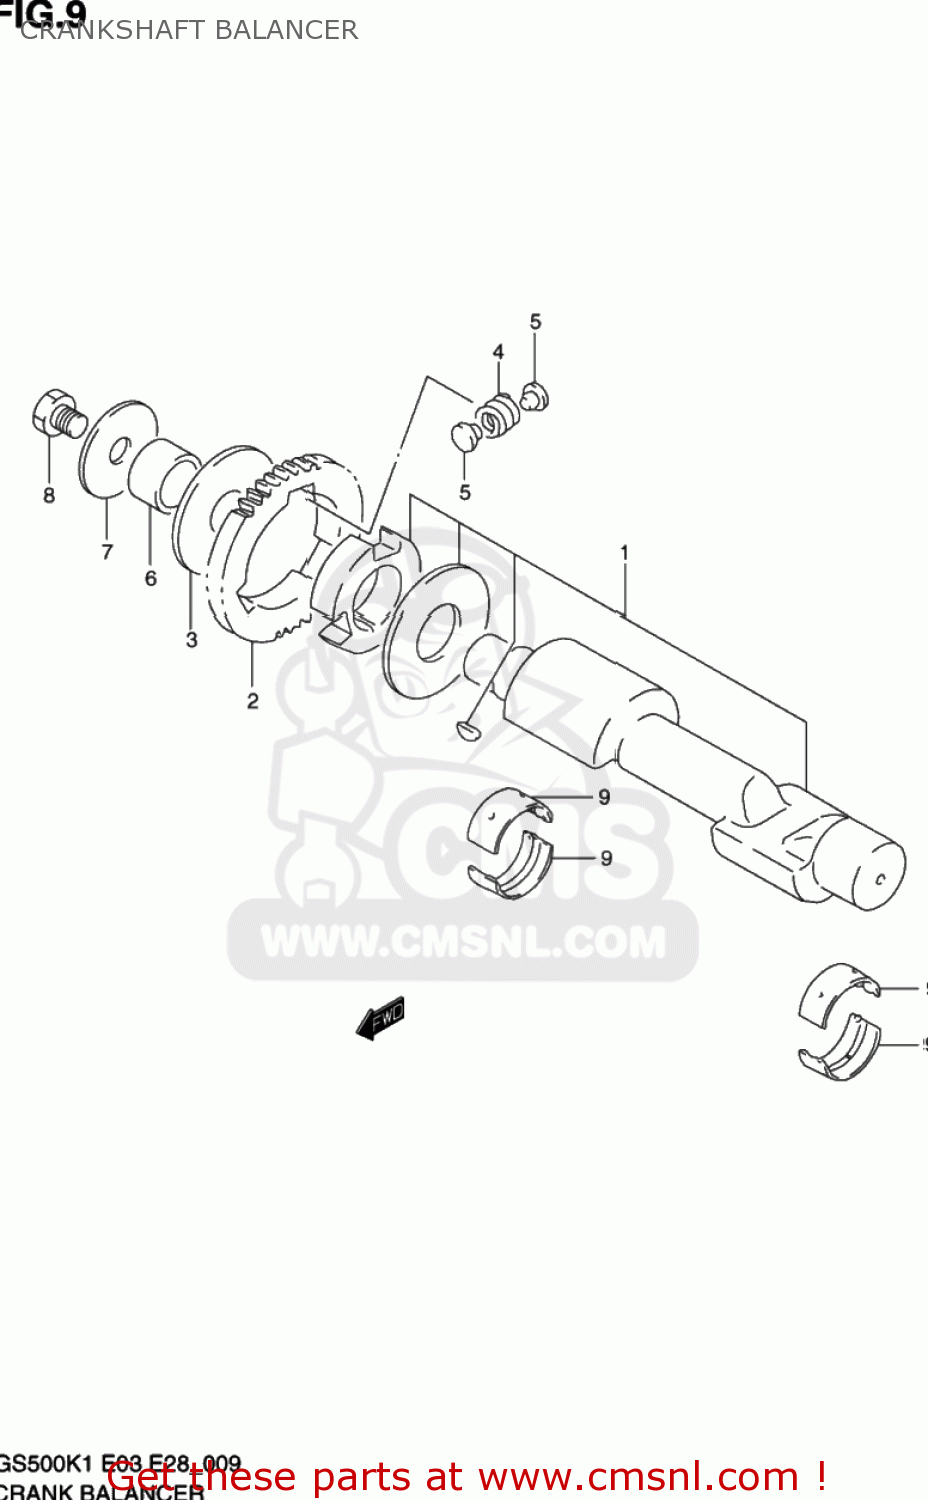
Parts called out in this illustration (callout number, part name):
1	BALANCER,CRANK
2	RACE,CRK BAL DRIVEN GEAR INNER
3	WASHER(24X70X3)
4	SPRING
5	PIN
6	SPACER(24X30.5X12.5)
7	WASHER(12X50X3)
8	BOLT
9	BEARING,CRANKSHAFT(GREEN)
